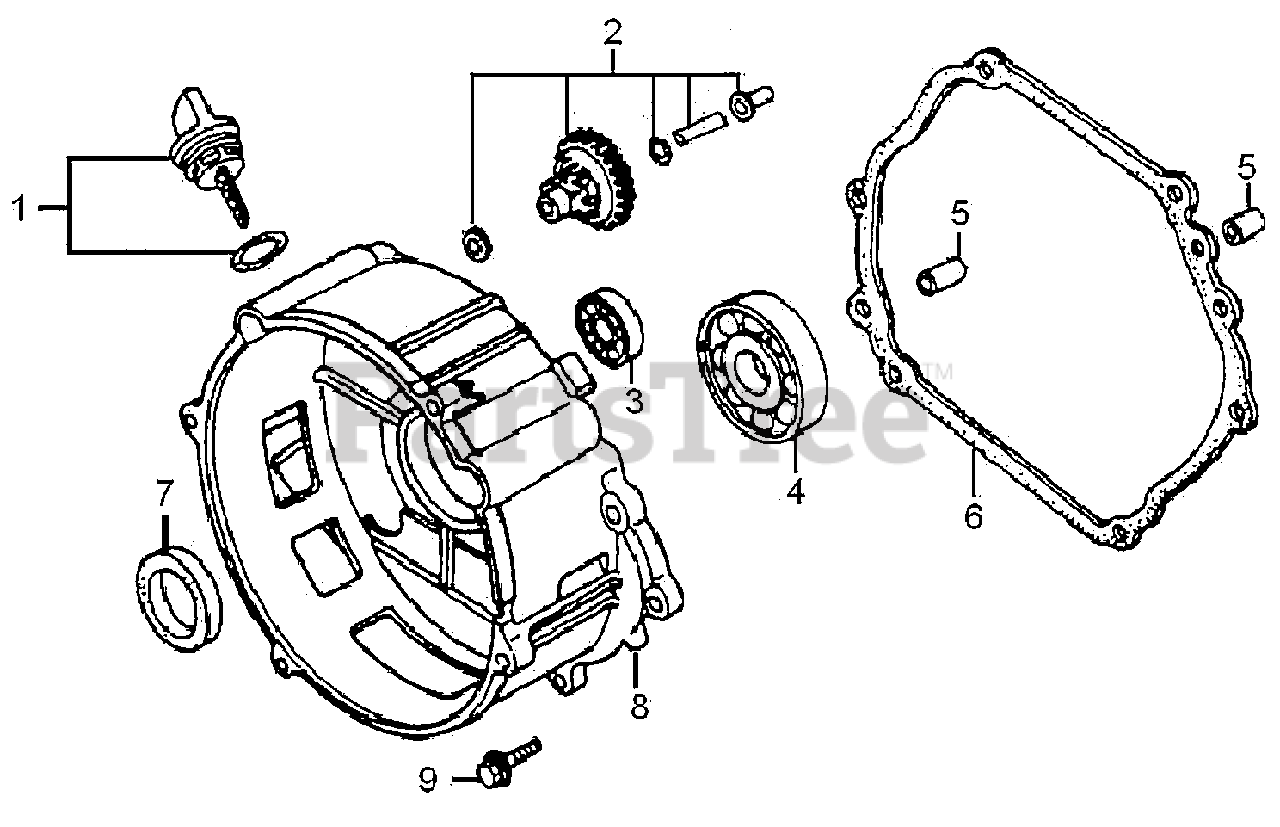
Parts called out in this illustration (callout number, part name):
1	CAP COMP., OIL FILLER
2	GOVERNOR ASSY.
3	BEARING, RADIAL BALL 6207
4	BEARING, RADIAL BALL 6202
5	PIN, DOWEL 8×12
6	PACKING, CASE COVER
7	OIL SEAL 35×52×7
8	CRANKCASE COVER
9	BOLT, FLANGE M8×40
